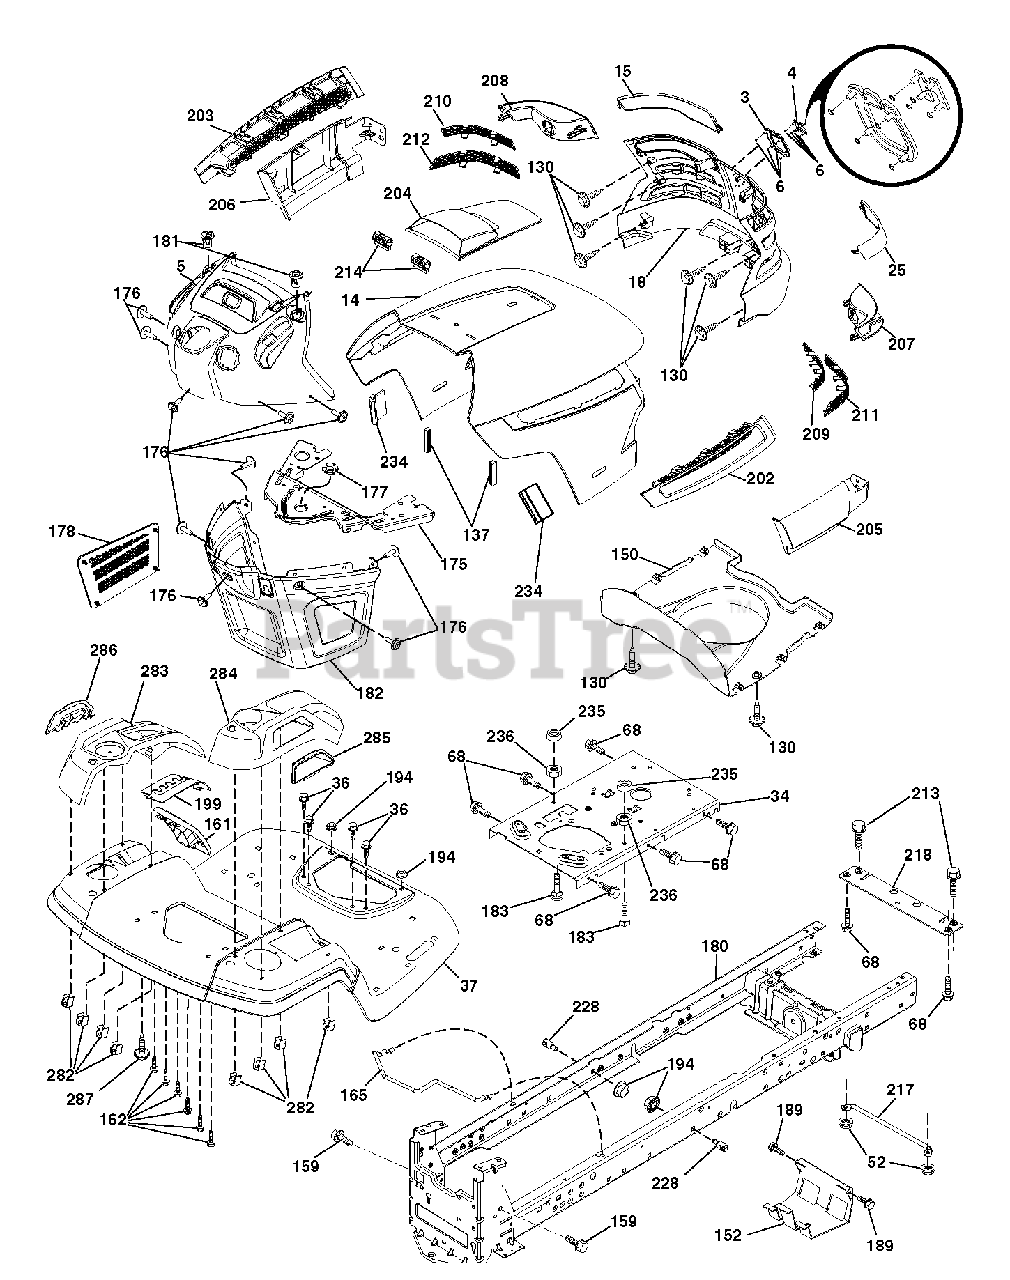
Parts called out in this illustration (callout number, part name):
3	TRIM.HUSQ.TG/CRD.SERVICE
4	RP LOGO
5	DASH ASM.HUSQ.GT.E.RDGA.N/CK.
6	NUT PUSH M
14	HOOD
15	LENS.LH.TEX.GT.HUSQ.CL
18	GRILL.ASM.HUSQ.TG/CRD.W/TRIM
25	LENS.RH.TEX.GT.HUSQ.CL
34	PLATE.ENGINE.WELDED.CHASSIS
36	SCREW 5/16"
37	FENDER.TLT.FS.W/CPH/FW/RSF.668
52	LOCKNUT
68	SCREW LT
130	SCREW.#10 X 0.750.BOS
137	BUMPER DASH
150	AIR.DUCT.HOOD.TEX.GT.HUSQ
152	SHIELD.BROWNING.W/TEX
159	SCREW, 3/8-16X3/4
161	WINDOW FUEL
162	SCREW.HI-LO.CONSOLE
165	SUPPORT.TANK.REAR.W/TEX
175	PLATE.CROSSMEMBER.HUSQ
176	SCREW.#10-24X5/8.RN.QU
177	BUSHING, STEERING
178	CARGO.ASM.NET.TXGT.W/C
180	CHASSIS
181	BUSHING.MNT.FEND.CRGO.
182	DASH.LOWER.COMMON.12V.ADAPTOR
183	BOLT.5/16-18X1-1/4 FULL THD
189	SCREW
194	NUT LOCK HEX FLANGE 5/16-18
199	PLATE.DECK.LIFT.HUSQ.LT
202	VENT.SIDE.HOOD.RH.HUSQ
203	VENT,SIDE.HOOD.LH.HUSQ
204	HOOD VENT
205	HOOD SIDE SKIRT RH
206	SKIRT.HOOD.SIDE.HUSQ.L
207	BEZEL.RH.TEX.GT.HUSQ
208	BEZEL.LH.TEX.GT.HUSQ
209	INSERT.HEX.GRILL.HUSQ.GREY
210	INSERT.HEX.GRILL.HUSQ.
211	INSERT.HEX.GRILL.HUSQ.
212	INSERT.HEX.GRILL.HUSQ.
213	BOLT
214	CLIP.RETAINER.TINNER.
217	ROD.PIVOT.HOOD
218	X-PIECE.HOOD.STOP.NON/
228	STUD.FASTNER.W/ANTI-ROTATE
234	BUMPER.HOOD.TEX.HUSQVARNA
235	SPACER FENDER
236	NUT.CENTERLOCK.5/16-
282	CLIP.RETAINER.CONSOLE.LT.HUSQ
283	CONSOLE.DECK.LFT.R.SDFL.HUSQLT
284	CONSOLE.CNTRL.
285	CONSOLE INSERT RH
286	CONSOLE.INSRT.LH.HUSQ.LT.BLACK
287	SCREW 1/4X20
